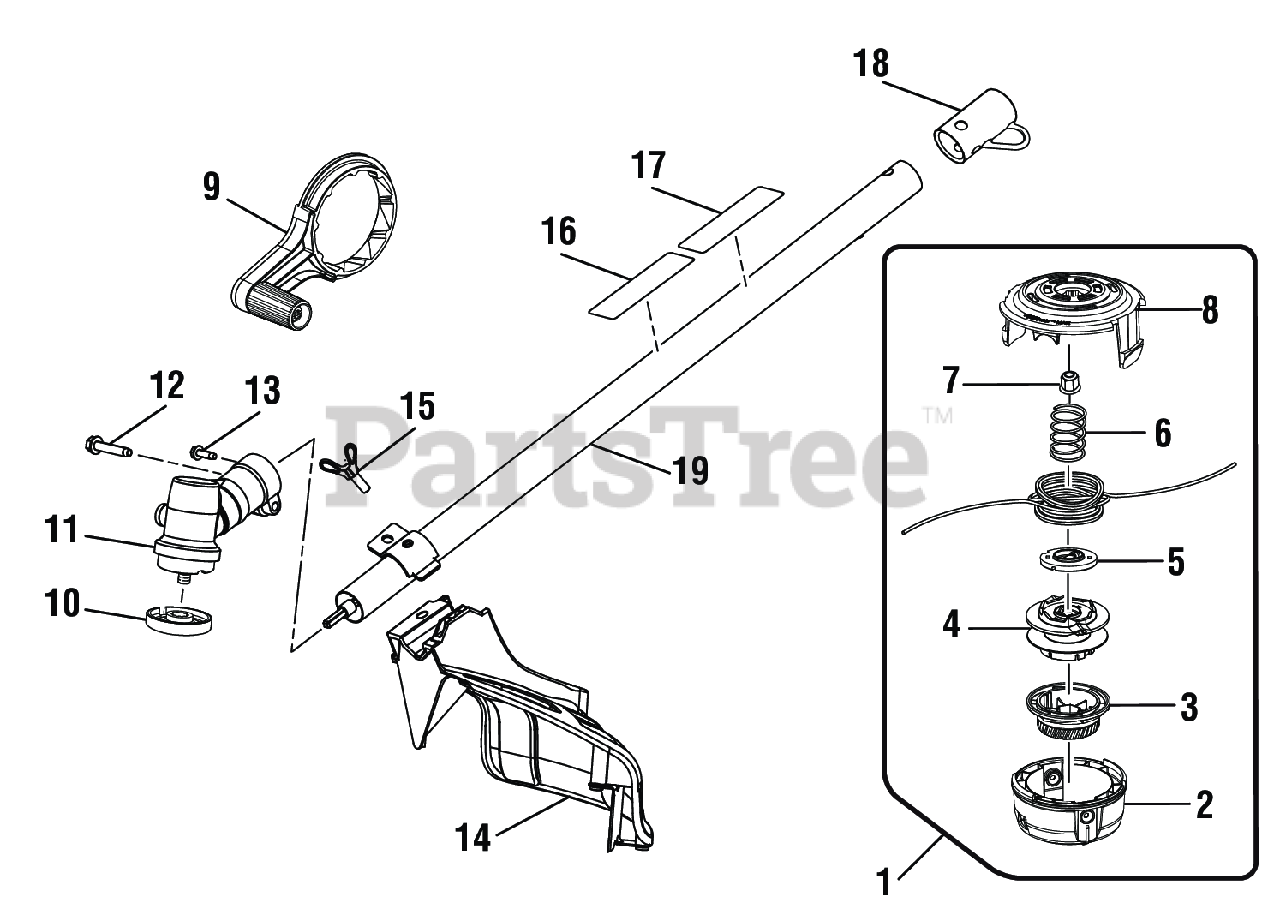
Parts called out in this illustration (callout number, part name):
1	Trimmer Head Assembly (.095)
2	Lower Housing
3	Bump Knob (Green)
4	Spool Assembly
5	String Guide
6	Compression Spring
7	Hex Nut (M8, Left Hand Threads)
8	Upper Housing
9	Crank Handle Assembly
10	FLANGED WASHER
11	Gear Case Assembly
12	Screw (1/4-20 x 1-1/4 in., Hex Washer Hd. S.T.)
13	Screw w/Washer (10-24 x 5/8 in., Hex Hd. T.F.)
14	Grass Deflector Assembly (Inc. Key No. 16)
15	Screw (#1/4-20 x 1-1/4 in. Hex Washer Hd.)
16	Ryobi EXPAND-IT Label
17	Warning Icon Label
18	Storage Hanger Cap
19	Straight Shaft Assembly
